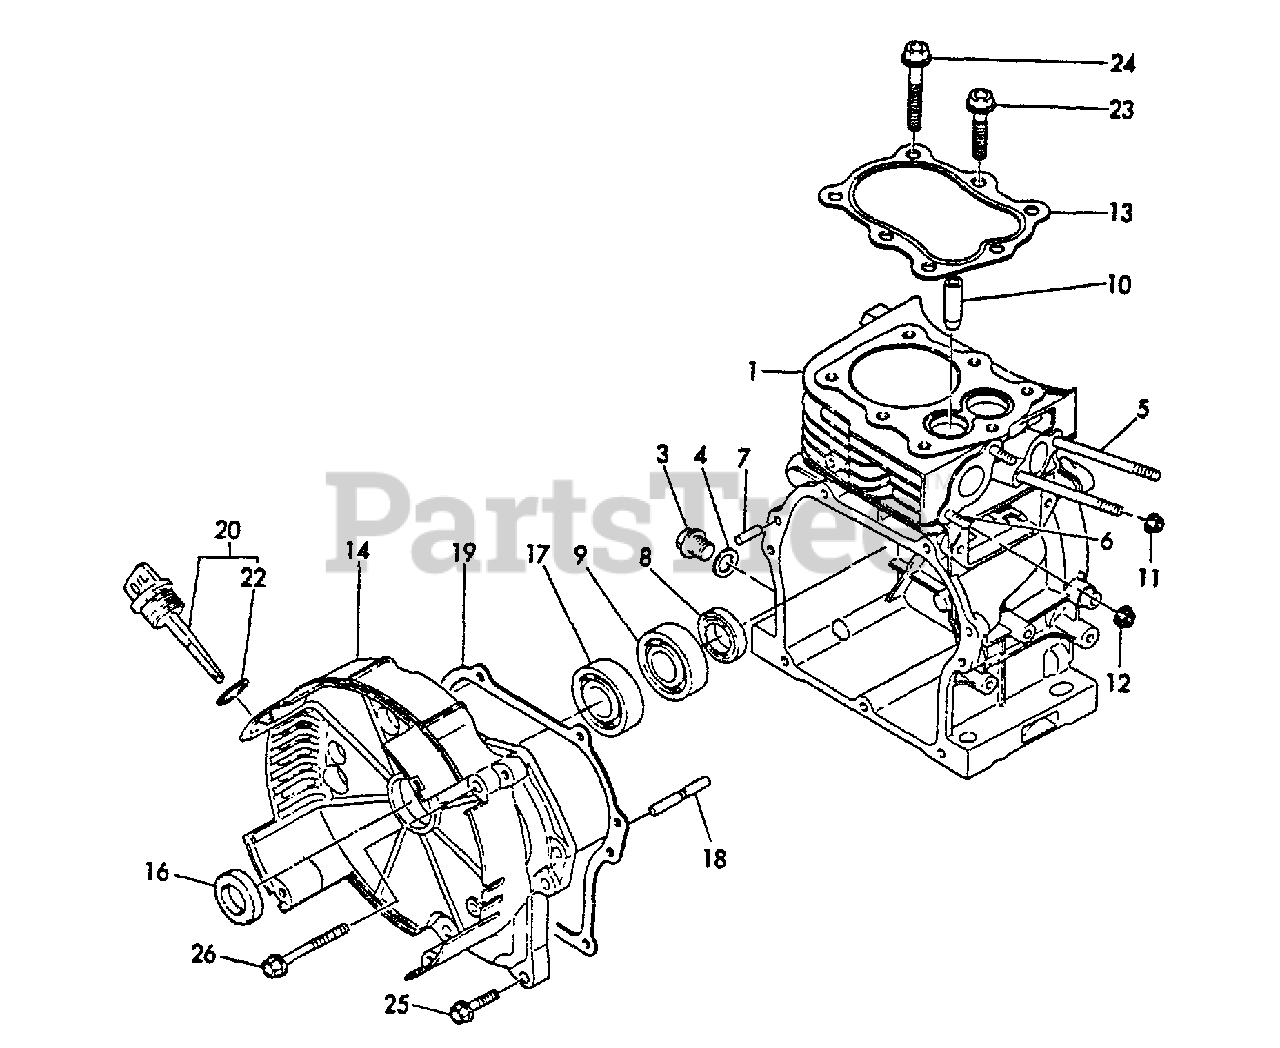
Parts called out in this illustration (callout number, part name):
1	CYLINDER BLOCK SET
3	PLUG, DRAIN
4	GASKET
5	BOLT - 6X70
6	BOLT - 6X16
7	PIN - 6X16
8	SEAL, OIL
9	BEARING, BALL - 6204C3
10	GUIDE, VALVE
11	NUT - 6 -- FLANGE
12	NUT - 6 -- FLANGE
13	GASKET, CYLINDER
14	SIDE COVER ASSY
16	SEAL, OIL
17	BEARING, BALL - 6204C3
18	SHAFT, GOVERNOR
19	GASKET
20	CAP ASSY
22	O-RING - 18
23	BOLT - 8X38
24	BOLT - 8X60
25	BOLT - 6X25
26	BOLT - 6X55
